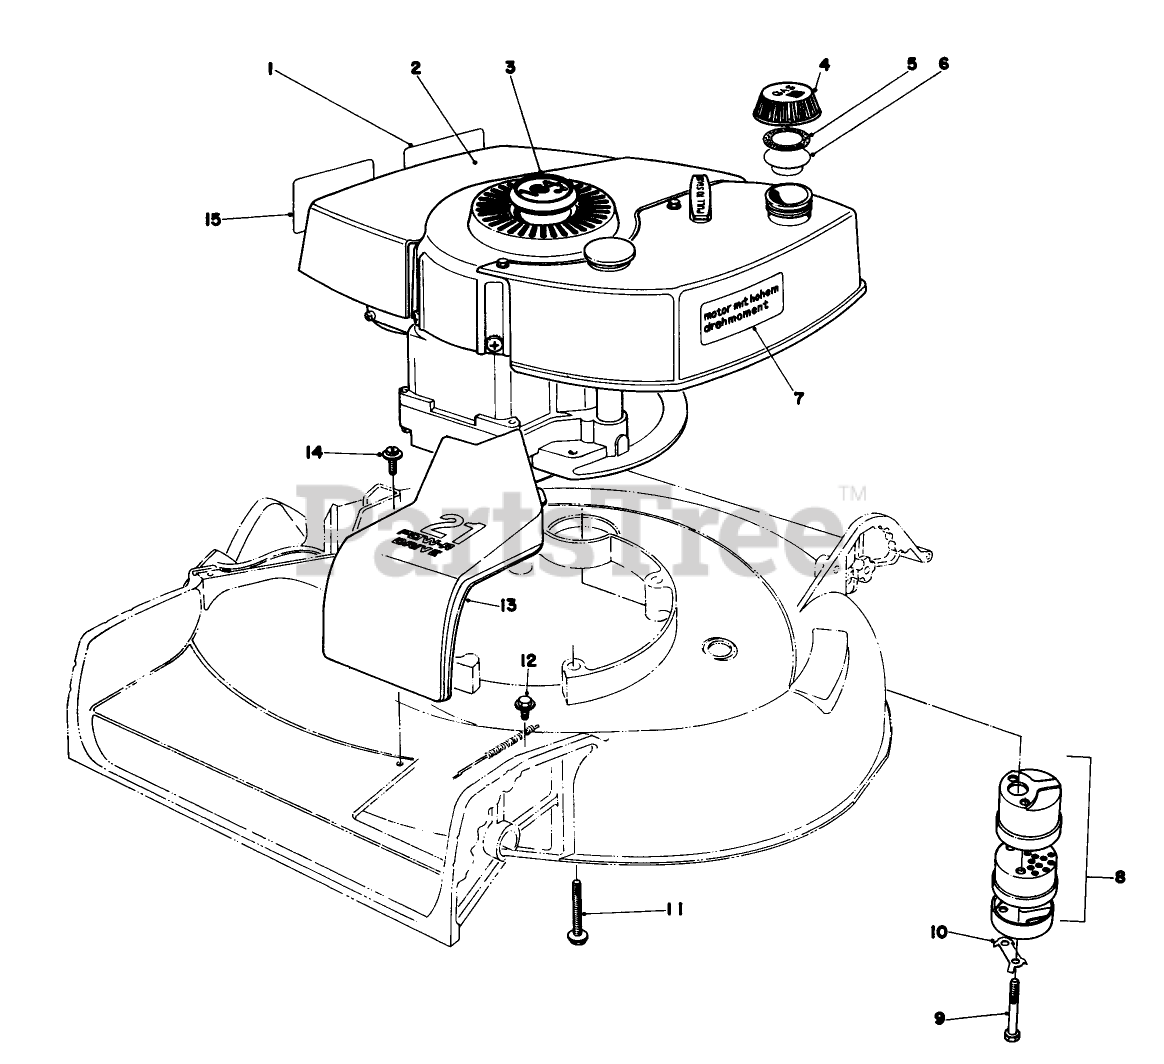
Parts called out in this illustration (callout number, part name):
2	Engine
5	GASKET
7	Decal Torque
8	MUFFLER ASM
9	SCREW-HH
10	CLIP - LOCKING
11	3/8-16 X 2-3/4 CAPSCR
12	SCREW-THD ROLL, HWH
13	BELT DRIVE COVER
14	SCREW
